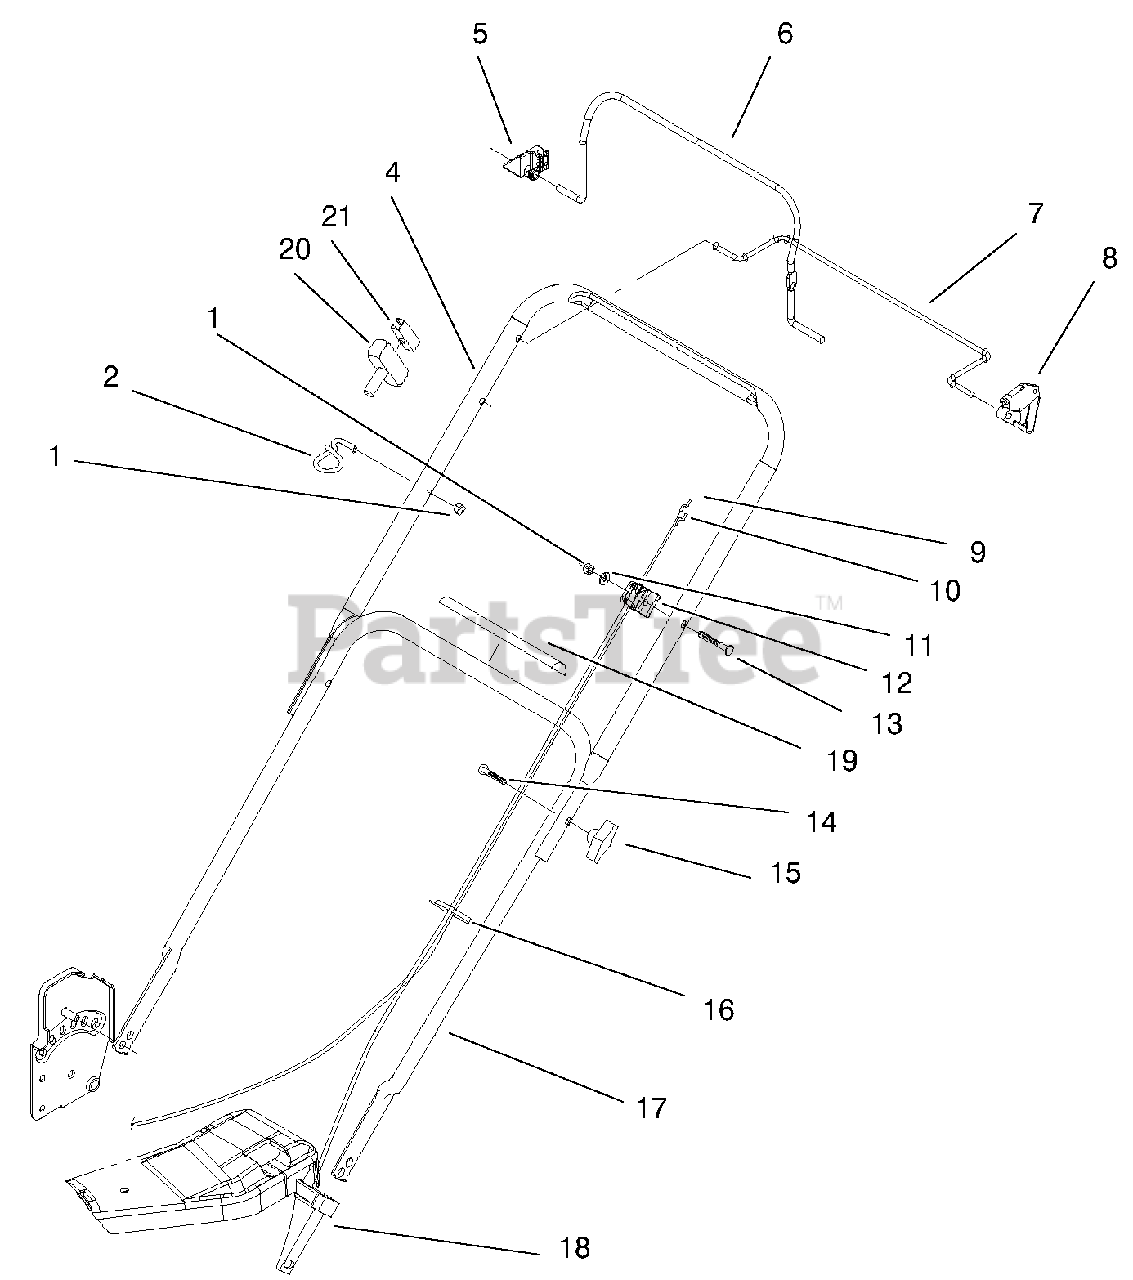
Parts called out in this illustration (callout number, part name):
1	Nut-Lock, NI
2	Guide-Rope
4	Handle-Upper
6	Bail-Brake
7	Bail-Traction
8	Stop-Pivot
9	Cable-Traction
10	Brake Cable ASM
11	Washer-Flat
12	Anchor-Cable
13	Screw-Handle
14	Screw-Handle
15	Knob-Handle
16	Tie-Cable
17	Lower Handle
18	Anchor-Cable
19	Decal-Operation
20	Handle-Start
21	Starter-Clip
